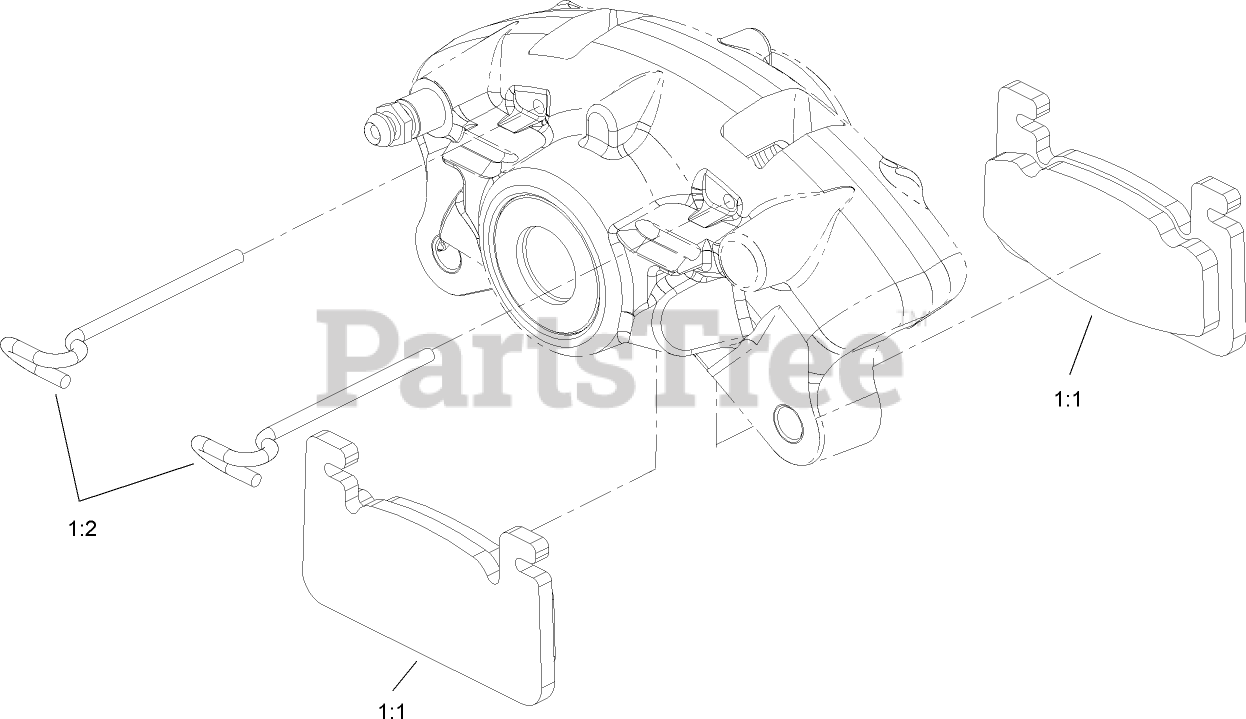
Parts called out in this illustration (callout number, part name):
1	FRICTION PAD AND PIN KIT
1:1	Loose Parts Package
1:2	Loose Parts Package
